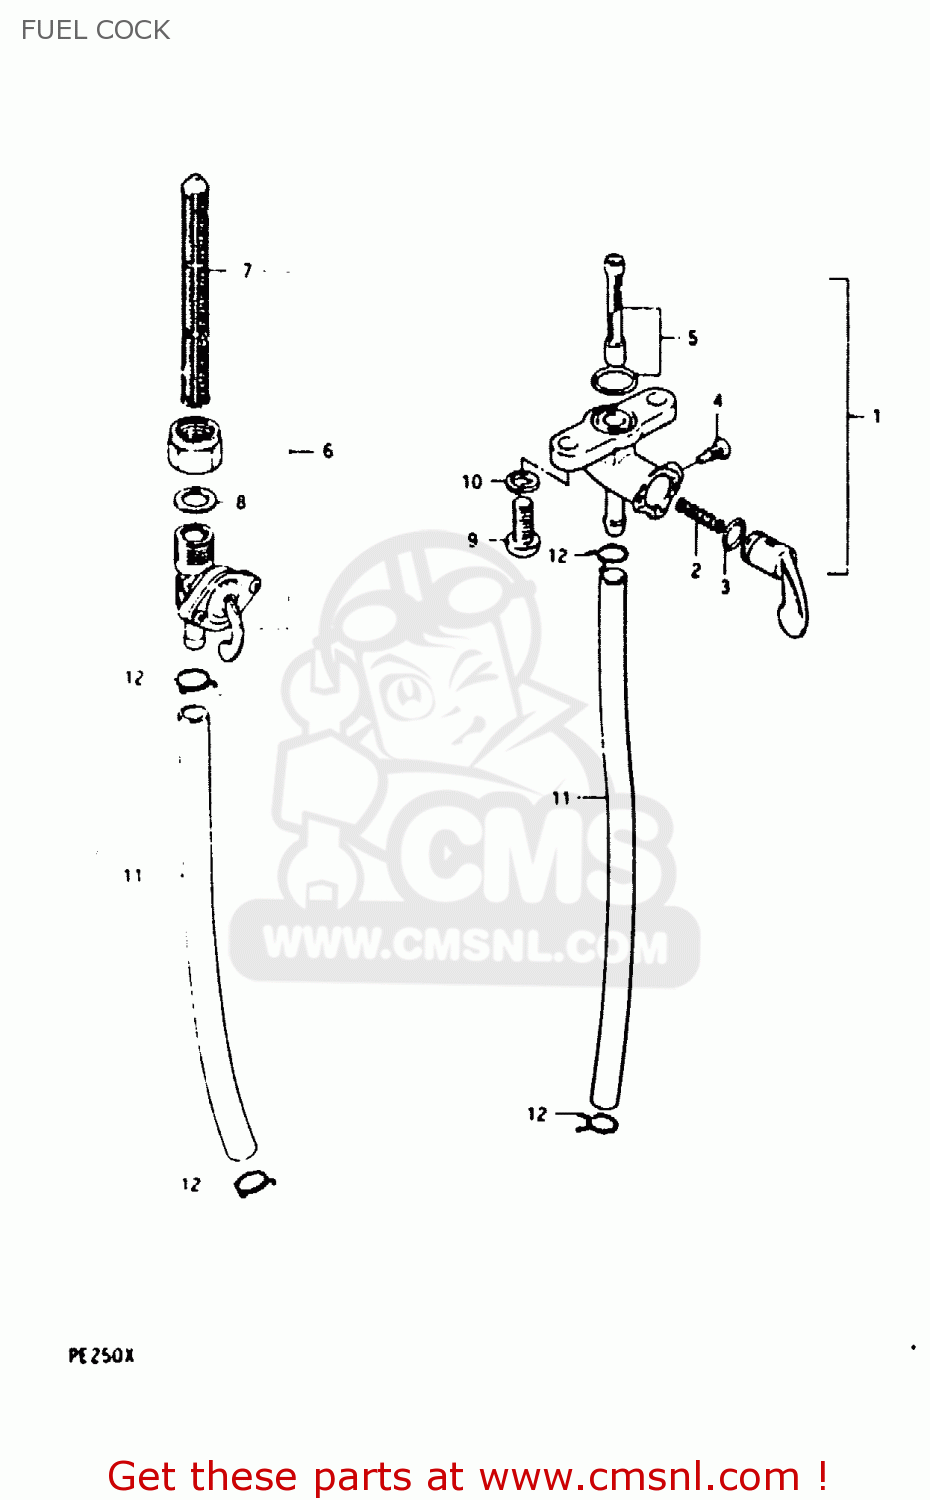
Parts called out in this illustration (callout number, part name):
6	COCK ASSY, FUEL
7	FILTER,FUEL
8	GASKET,FUEL COCK (NAS)
9	SCREW
10	LOCK WASHER
11	HOSE
12	CLAMP
